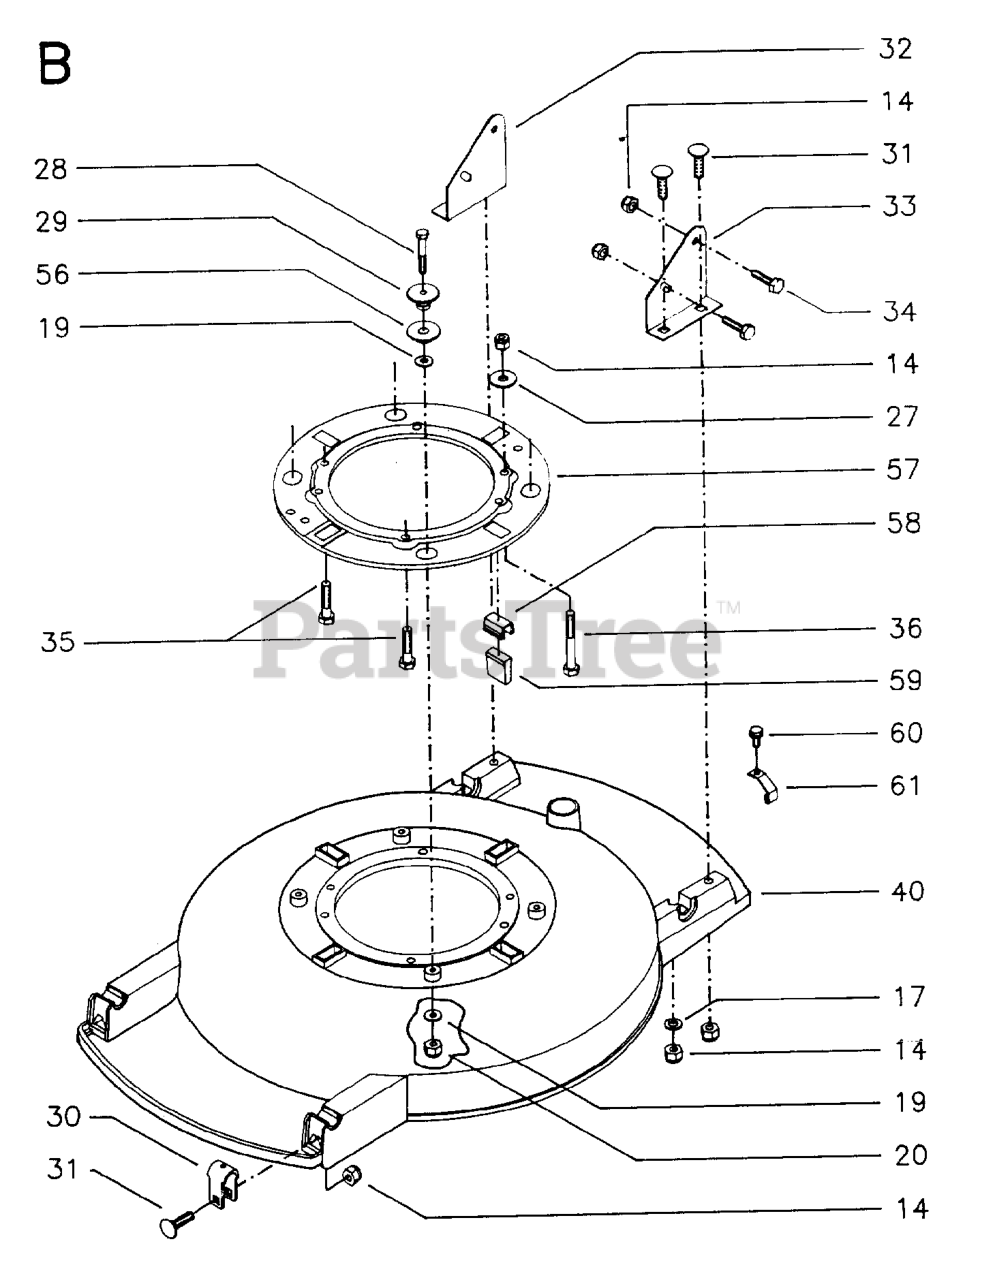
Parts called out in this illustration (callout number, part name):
14	LOCKNUT M8
17	WASHER - 15X7.3X1.6
20	LOCKNUT M6
30	BEARING HOLDER
32	HANDLE BRACKET
33	HANDLE BRACKET
34	BOLT - M8X16
56	RUBBER PIECE
59	DAMPER
